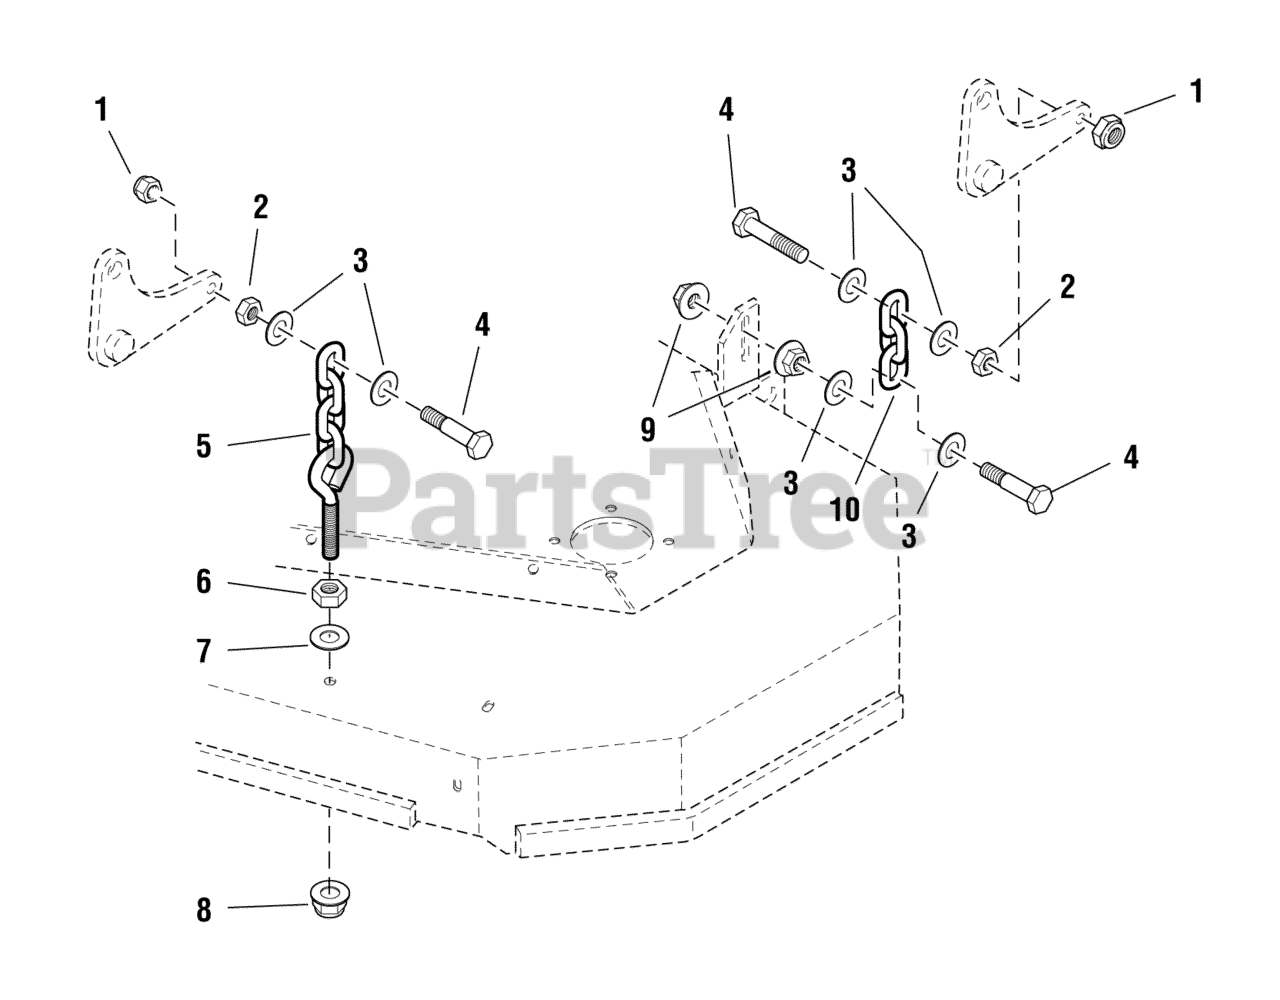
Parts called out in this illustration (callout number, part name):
1	NUT, 3/8-16 HEX NYLON LOCK
2	NUT, 3/8-16 HEX JAM
3	WASHER, 3/8 SAE
4	BOLT, 3/8-16 X 2, GD5, CZ
5	HANGER, FRONT DECK - 4 LINK, 5.5" EB
6	NUT, 1/2-13 HEX
7	WASHER, 1/2 SAE
8	NUT, 1/2-13 HEX NYLON LOCK
9	NUT, 3/8-16 HEX SERRATED FLANGE
10	CHAIN, 5/16" GD30, 3 LINKS
